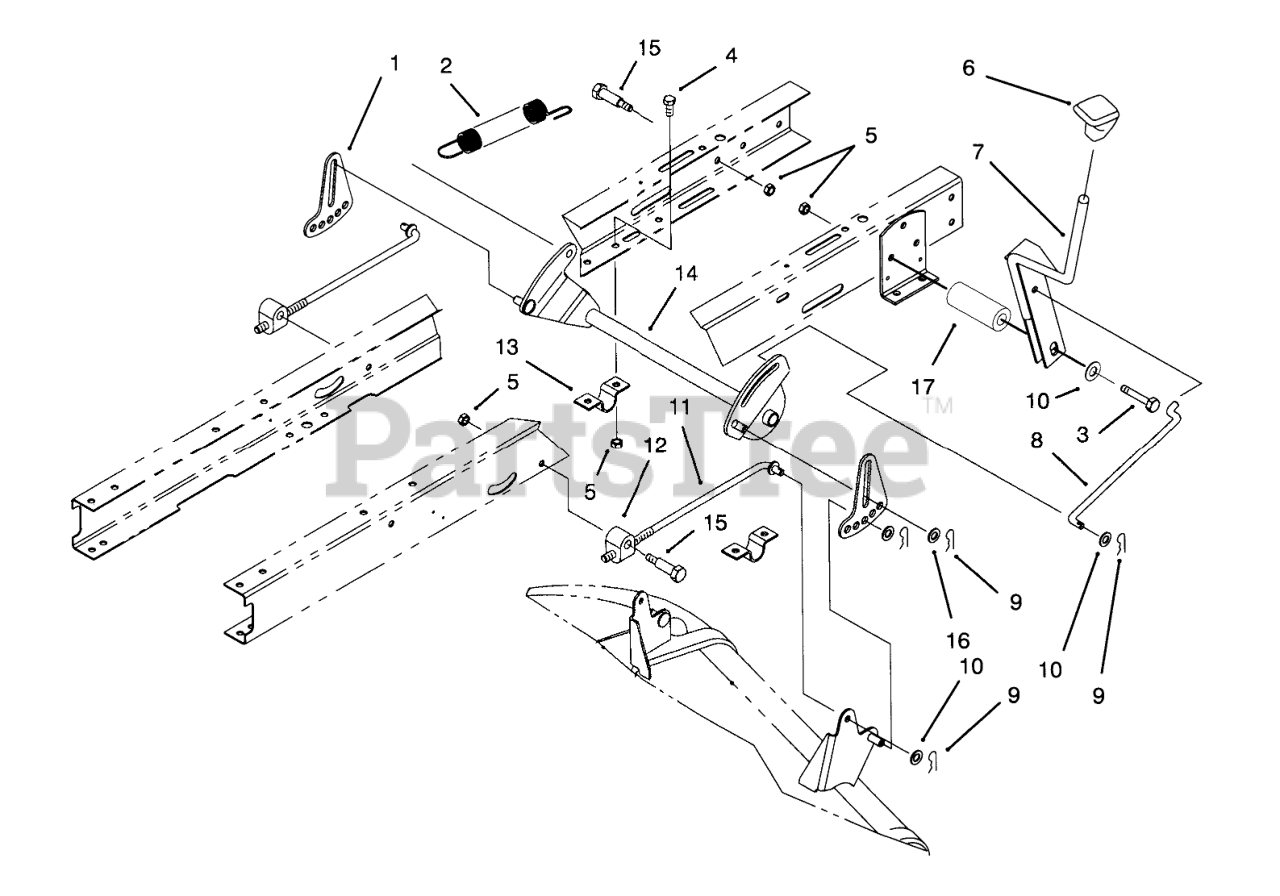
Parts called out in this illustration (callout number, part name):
1	Link-Adjusting H.O.C.
2	Spring-Extension
3	SCREW-HH
4	SCREW-HH
5	Nut-Lock
6	Knob-Shift
7	Lever-H.O.C.
8	Link-H.O.C.
9	Pin-Hair Cotter
10	WASHER-FLAT
11	ROD-HANGER, REAR
12	TRUNNION-HOC
13	CLAMP-PIVOT, HOC
14	Pivot-H.O.C.
15	SCREW-SHOULDER, HH
16	WASHER-HARDENED
17	SPACER
